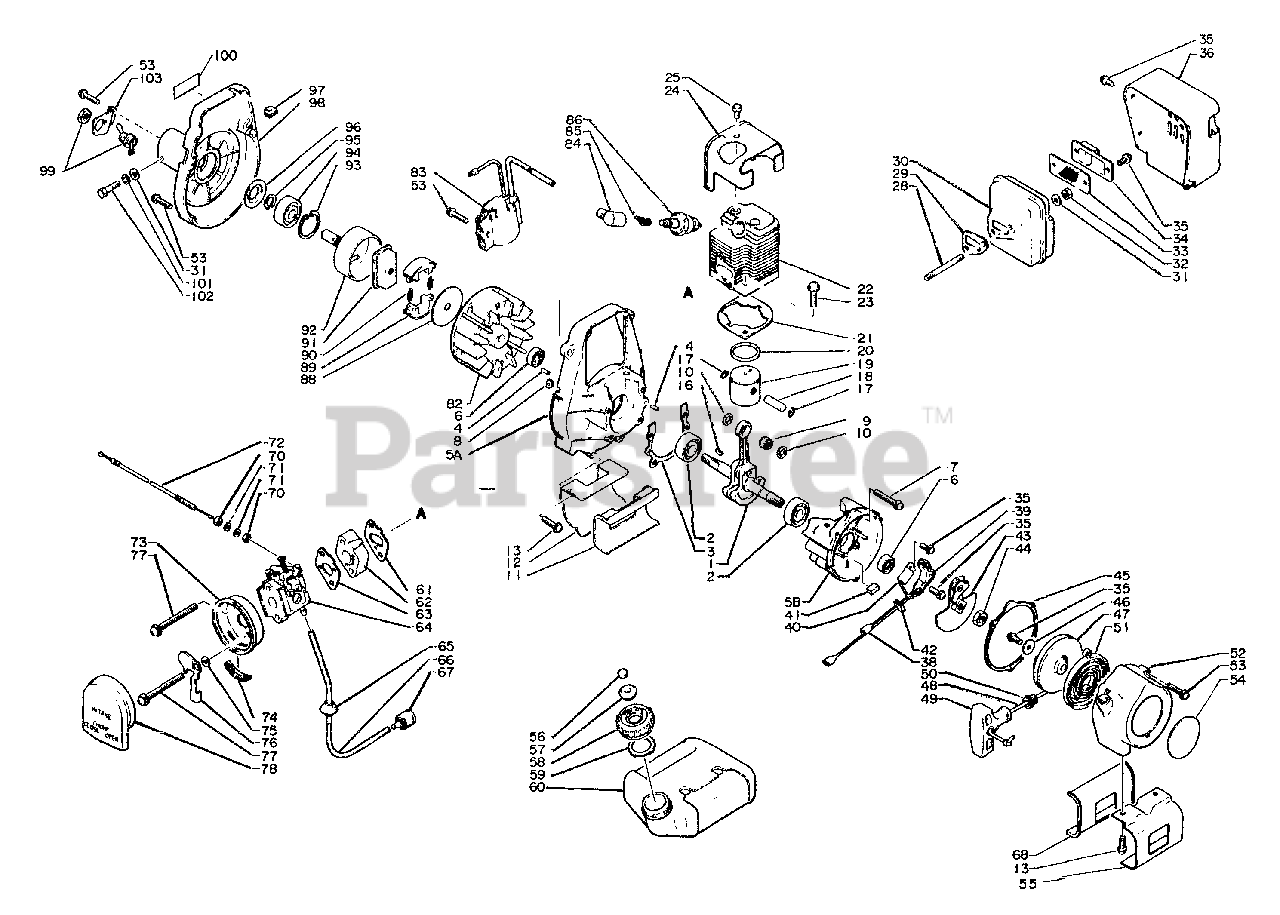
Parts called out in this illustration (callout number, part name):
1	CRANKSHAFT ASSY
2	BEARING, BALL - 6200
3	GASKET, CRANKCASE
4	PIN - LOCATING
5	CRANKCASE KIT
5A	CRANKCASE KIT
5B	CRANKCASE KIT
6	SEAL, OIL
7	SCREW - 5X30
9	BEARING, NEEDLE - 8
10	SPACER, PISTON
11	CUSHION
12	BRACKET, FUEL TANK
13	SCREW - 4X14
17	RING, RETAINING
18	PIN, PISTON
19	PISTON
20	RING, PISTON
21	GASKET, CYLINDER
22	CYLINDER
23	SCREW - 6X22
24	COVER, ENGINE
25	SCREW - 5X10
29	GASKET, EXHAUST
30	MUFFLER
31	WASHER - 5
32	LOCKNUT - 5
33	SCREEN, SPARK ARRESTOR
34	SCREEN, SPARK ARRESTOR
35	SCREW - 4X10
36	COVER, MUFFLER
38	LEAD - GROUND
39	CONTACT POINT SET
40	CONDENSER
41	PAD, OIL
43	STARTER PAWL ASSY
45	GASKET, STARTER
47	REEL, ROPE
48	ROPE, STARTER - 3X850
49	GRIP, STARTER
50	GUIDE, ROPE
51	SPRING, REWIND
52	CASE, STARTER
53	SCREW - 4X20
54	LABEL - ECHO
55	BRACKET, FUEL TANK
58	CAP
59	GASKET, CAP
60	TANK, FUEL
61	GASKET, INTAKE
62	INSULATOR, INTAKE
63	GASKET, INTAKE
64	CARBURETOR WA-81
66	PIPE - 3X5X150 -- BLACK
67	FILTER, FUEL
68	CUSHION
73	CASE, AIR FILTER
75	WASHER - 5
76	SHUTTER, CHOKE
77	SCREW - 5X57
78	FILTER, AIR
82	FLYWHEEL
83	COIL, IGNITION
84	CAP, SPARK PLUG
85	TERMINAL, SPARK PLUG CAP
86	SPARK PLUG -- BM-6A
88	PLATE, CLUTCH
89	SHOE, CLUTCH
90	SPRING, CLUTCH
91	HUB, CLUTCH
92	DRUM, CLUTCH
93	RING, RETAINING - 32
94	BEARING, BALL - 6201
95	RING, RETAINING - 12
96	RETAINER, PIPE
98	CASE, FAN
99	IGNITION SWITCH KIT
100	LABEL - NAME
101	LOCKWASHER - 5
102	BOLT - 5X25
103	BRACKET, SWITCH
